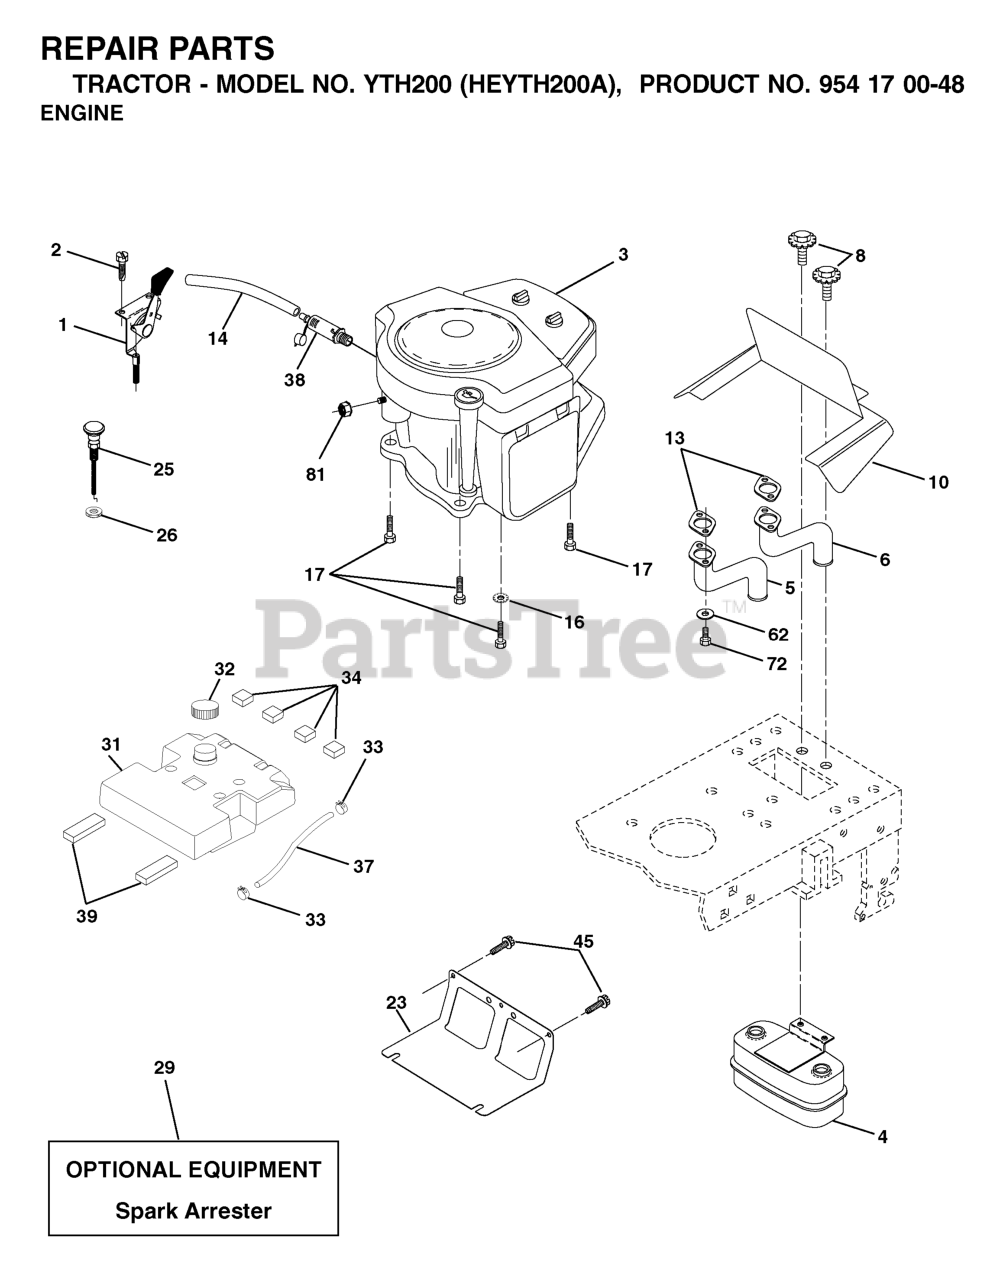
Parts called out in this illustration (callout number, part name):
1	CONTROL, THROTTLE
2	SCREW
4	MUFFLER.TWIN.CYL.LOW.TONE
5	RP.EXHAUST.TUBE.LH.BS/TWIN
6	EXHAUST.TUBE.RH.BS/TWIN
8	BOLT.5/16-18UNCX3/4 W/SEMS.BLK
10	SHIELD.BROWNING.B&S
13	GASKET.MUFFLER
14	TUBE, DRAIN OIL ASM.
16	LOCKWASHER
17	SCREW 3/8-16 X 1-1/2
23	SHIELD.BROWNING.DBR.GUARD
25	CONTROL, CHOKE
26	Nut Keps 3/8 - 24 UNF
29	KIT.SPARK ARRESTOR 794945 B&S
31	TANK.FUEL(3.5.GAL)
32	FUEL CAP
33	HOSE CLAMP
34	PAD-SPACER LT
37	REPL BY 532 00 85-43
38	PLUG, OIL DRAIN EASY
39	PAD IDLER TI
45	SCREW, 3/8-16X3/4
62	WASHER.LOCK.HVY.HLCL.SPR.5/16
72	SCREW
81	NUT
